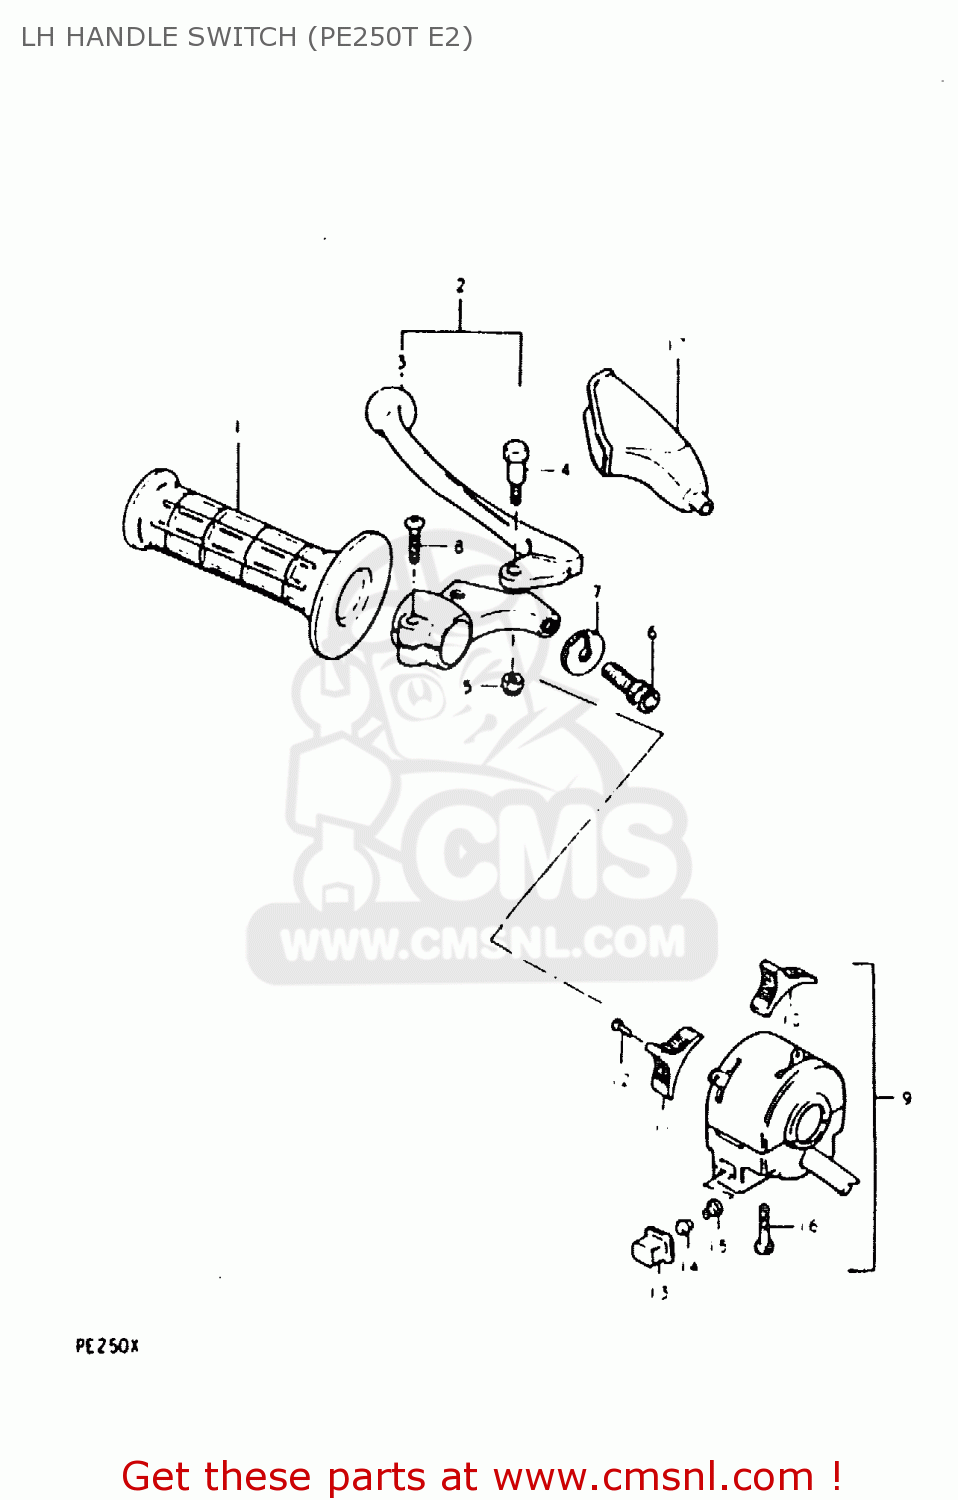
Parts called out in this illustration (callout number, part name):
1	GRIP,LEFT
2	LEVER ASSY,CLUTCH
3	LEVER,CLUTCH
4	BOLT,LEVER
5	NUT 6MM
6	ADJUSTER,CABLE
7	NUT,CABLE ADJUSTER
8	SCREW
9	SWITCH ASSY, HANDLE LH
10	KNOB,LIGHTING SWITCH
11	KNOB,DIMMER SWITCH
12	SCREW
13	BUTTON,HORN
14	CONTACT
15	SPRING
16	SCREW
17	COVER,CLUTCH LEVER
